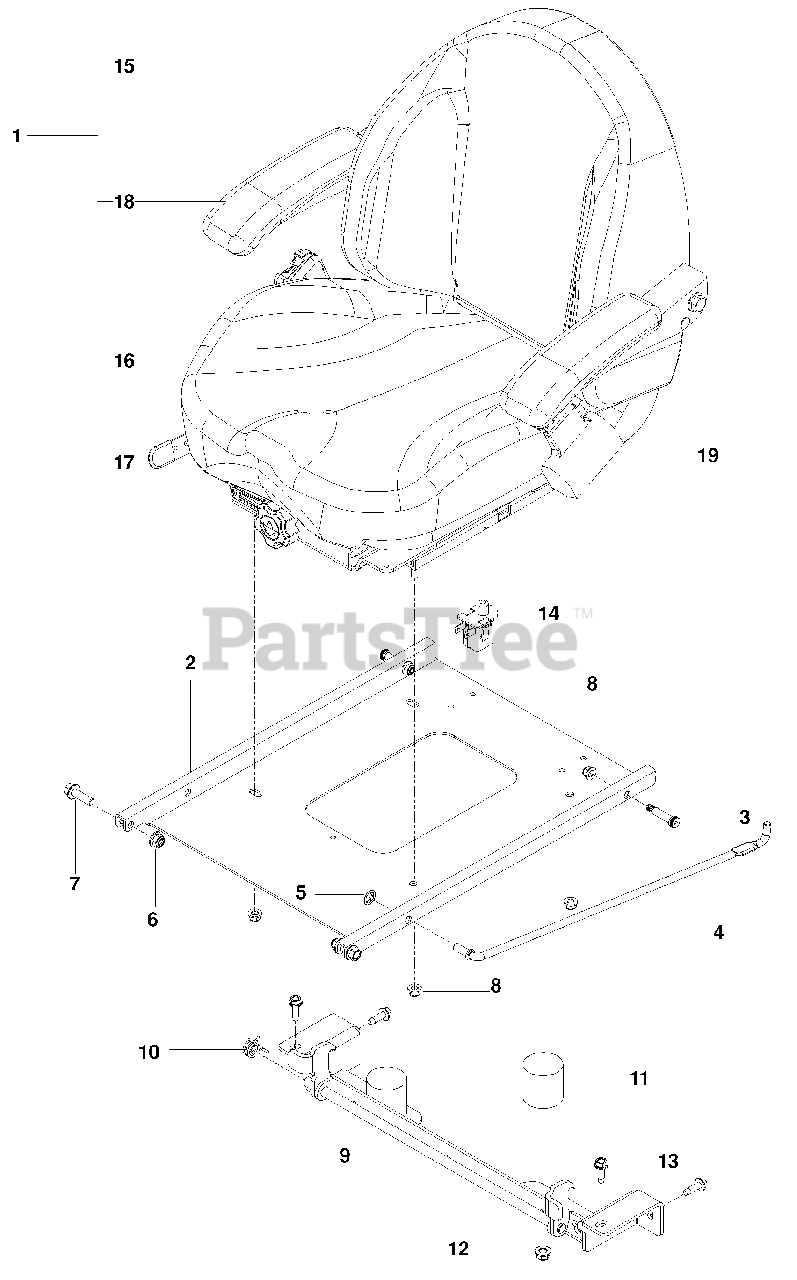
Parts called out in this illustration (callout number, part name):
1	Seat Assy
2	Bolt 7/16-20 X 1 1/2 Hex Nyl
3	Bolt 3/8 X 1 1/4 5/16-18 Shldr
5	Retainer Nut 3/8
6	Nut 3/8-16 Hex Flg Nyloc
7	Screw 3/8-16 X 1 1/4 Hex Flg
8	Nut 5/16-18 Hex Flg Nyloc
9	Latch, Seat
10	Spring, Torsion
11	Bumper, Rubber
12	Nut 3/8-16 Hex Flg Nyloc
13	Bolt 5/16-18 X 1 Thd Frm
14	Switch, Seat
15	Cover, Back
16	Cover Kit, Cushion
18	Armrest, Lt
19	Seat Belt
